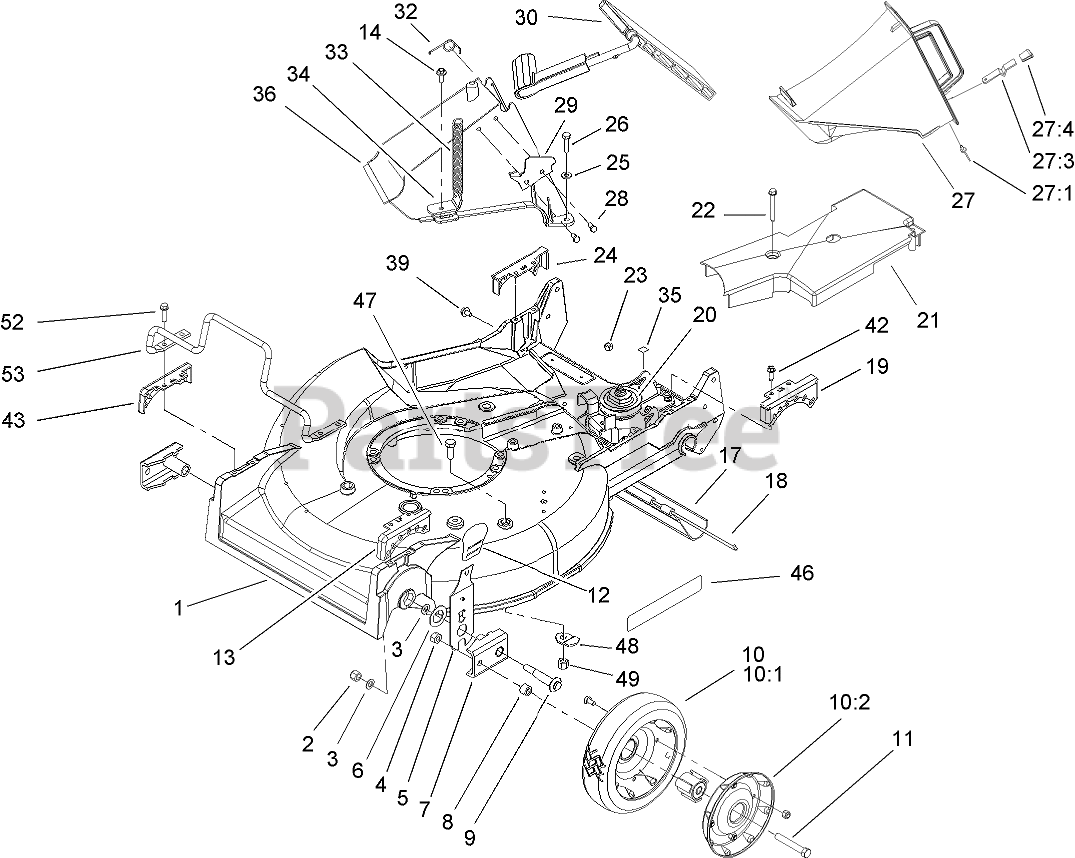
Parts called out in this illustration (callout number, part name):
1	HOUSING
2	NUT-LOCK
3	WASHER
4	NUT-LOCK, CONE
5	SPRING ARM ASM
6	WASHER-THRUST
7	ARM-PIVOT, FRONT
8	SPACER-WHEEL
9	BOLT-WHEEL
10	Wheel and Tire ASM
10:2	Wheel ASM
11	SCREW-HH
12	KNOB-HOC
13	QUADRANT-FRONT, LH
14	SCREW-HWH
17	SHIELD-TRAILING
18	ROD-SHIELD
19	QUADRANT-REAR, LH
20	GEAR CASE ASM
21	COVER-BELT
22	SCREW-HHFTF
23	NUT-LOCK, NI
24	QUADRANT-REAR, RH
25	WASHER-FLAT
26	SCREW-HH
27	DISCHARGE PLUG ASM
27:1	RIVET-HEAD, FLAT
27:3	LATCH-PLUG, DISCHARGE
27:4	GRIP-LATCH
28	SCREW-PLASTITE
29	LATCH-PLATE
30	DISCHARGE DOOR ASM
32	RETAINER-DOOR
33	SPRING-DOOR
34	BRACKET-SPRING
35	DECAL-GREASE
36	TUNNEL-DISCHARGE
39	SCREW AND WASHER ASM
42	SCREW-HWHTF
43	QUADRANT-FRONT, RH
47	SCREW-HH
48	SHIELD-RETAINER
49	NUT-LOCK, NI
52	SCREW-HWHTF
53	GUARD-ENGINE
